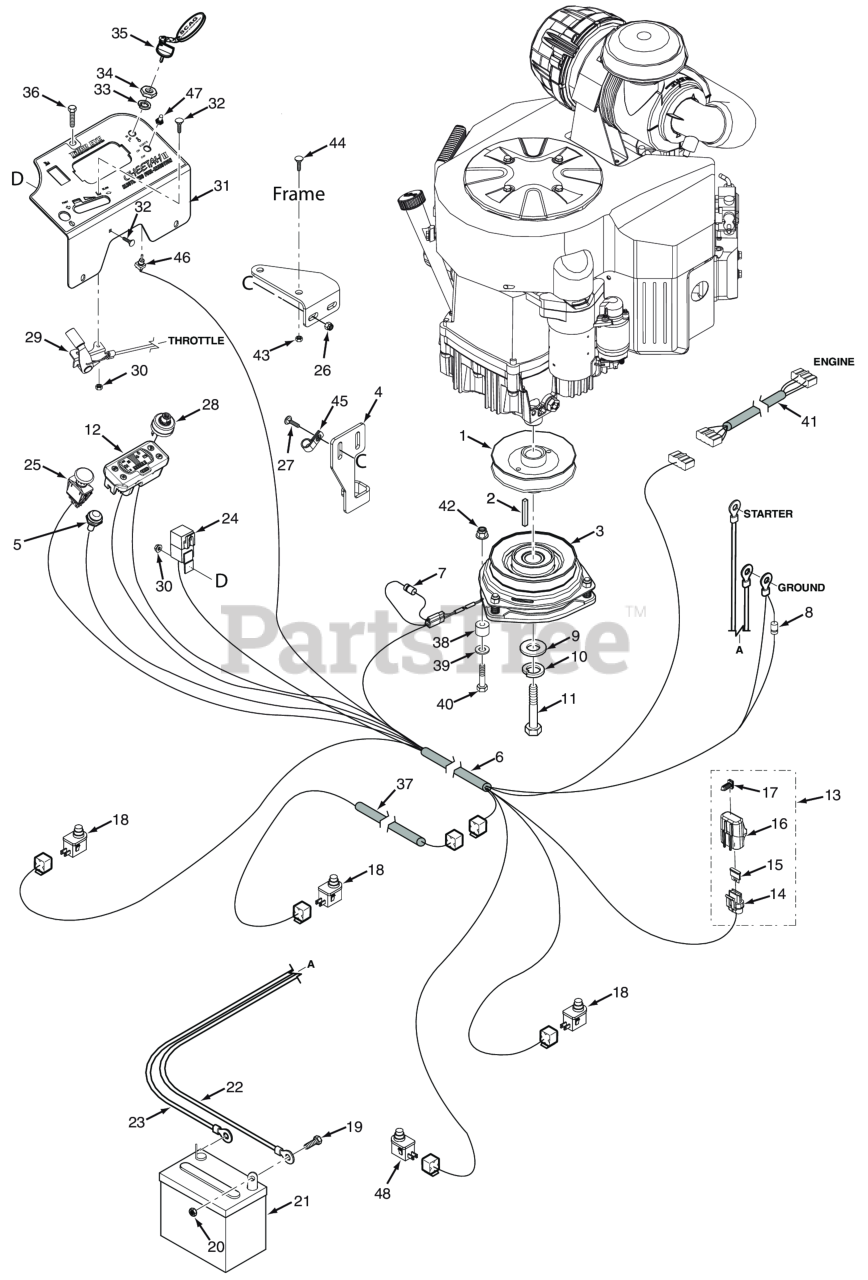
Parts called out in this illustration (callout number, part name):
1	Pulley, 5.80" Dia. - 1.125 Bore
2	Key, 1/4 x 1/4 x 3-1/4�
3	Electric Clutch w/Tag - GT-5 (ECV860, ECV940)
4	Bracket, Anti-Rotation
5	Indicator Light, Glow Plugs (Includes Mounting Hardware)
6	Wire Harness, SCZII-EFI
7	Diode, 600V 6 Amp
8	Decal, Forward Speed Selector
9	Flatwasher, 7/16-.469 x 1.75 x .25 (48, 52)
10	Lockwasher, 7/16� Spring
11	Bolt, Hex Head 7/16-20 x 2-1/4" w/Patch (Kawasaki)
12	Tiger Eye, Cluster Gauge
13	Single Fuse Assy., Excluding Fuse
14	Fuse Holder Assembly
15	FUSE, 20 AMP BLADE TYPE AUTOMOTIVE
16	Cover, Sealed Single
17	Clip, Fuse Holder
18	Switch, Interlock, Normally Open
19	Bolt, Hex Head 1/4-20 x .5" Battery, (Not Available Through Scag)
20	Nut, 1/4 - 20 Hex
21	Battery
22	Battery Cable, 18" Black (Kohler)
23	Battery Cable, 25" Red
24	Relay, 12V 40 AMP Standard
25	Switch, PTO - 10 Amp
26	Nut, Flange Head Elastic Stop 5/16-18
27	Bolt, Carriage 5/16-18x1" (large frame units only)
28	KEY SWITCH(INCLUDES MOUNTING HARDWARE)
29	Control Cable (Kawasaki FX921 Throttle & Choke Cable)
30	Nut, Elastic Stop #10-24
31	Instrument Panel w/Decal
32	Bolt, Carriage #10-24 x 1/2"
33	LOCK WASHER, 5/8" INTERNAL TOOTH
34	Nut, 5/8-32 Special
35	Key, Assembly w/Fob
36	CAP SCREW, 1/4-20 X 1/2" SERRATED FLANGE HEX
37	Wire Harness, Operator Platform -SCZ
38	Bushing, UHMW
39	Flatwasher, 5/16-.375 x .875 x .083 (35BV & 37BV-EFI)
40	Bolt, Hex Head 5/16-18 x 1-1/2" (Right Front Engine Mounting, Briggs and Kohler Only)
41	Wire Harness Adapter, Briggs & Stratton 37 BV-EFI
42	HEX NUT, ELASTIC STOP LOCK, 5/16-18
43	NUT, 3/8-16 SERRATED FLANGE HEX HEAD
44	Carriage Bolt, 3/8-16 x 1.0"
45	Clamp, Cable 1/2" I.D.
46	SWITCH, ON / OFF
47	BOOT, SWITCH
48	Switch, N/C
